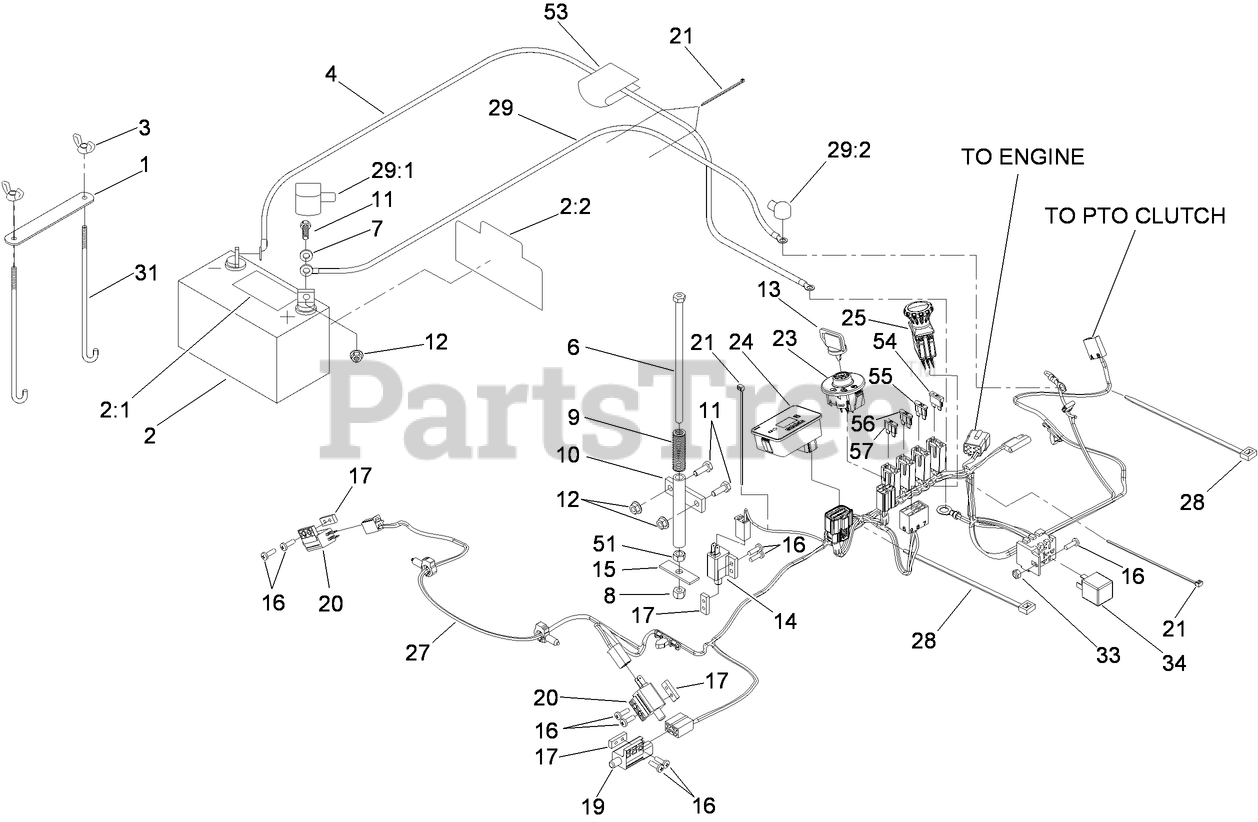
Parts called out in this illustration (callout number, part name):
1	STRAP-HOLDDOWN, BATTERY
2	BATTERY
2:1	Decal-Battery
2:2	Decal-Battery
3	WINGNUT
4	WIRE-GROUND
6	SCREW-HH
7	WASHER-FLAT
8	NUT-LOCK, NI
9	SPRING-SWITCH, SEAT
10	MOUNT-SPRING, SEAT
11	SCREW-HH
12	NUT-HF
13	KEY-IGNITION
14	SWITCH-CLOSED, NORMALLY
15	PLATE-SWITCH, SEAT
16	SCREW-PPH
17	PLATE-TAPPED
19	SWITCH
20	SWITCH-OPEN, NORMALLY
21	TIE-CABLE
23	SWITCH-IGNITION
24	HOUR METER ASM
25	SWITCH-PTO, 10 AMP
27	HARNESS-ELECTRICAL
28	TIE-PLASTIC
29	POSITIVE BATTERY CABLE ASM
29:1	INSULATOR-BATTERY
29:2	INSULATOR-SOLENOID
31	BOLT-HOLDDOWN
33	NUT-LOCK, NI
51	NUT-HEX
53	DECAL-INSTRUCTIONS, CHARGING
54	FUSE-BLADE, 15 AMP
55	FUSE-BLADE, 30 AMP
56	FUSE-BLADE, 25 AMP
57	FUSE-BLADE, 10 AMP
